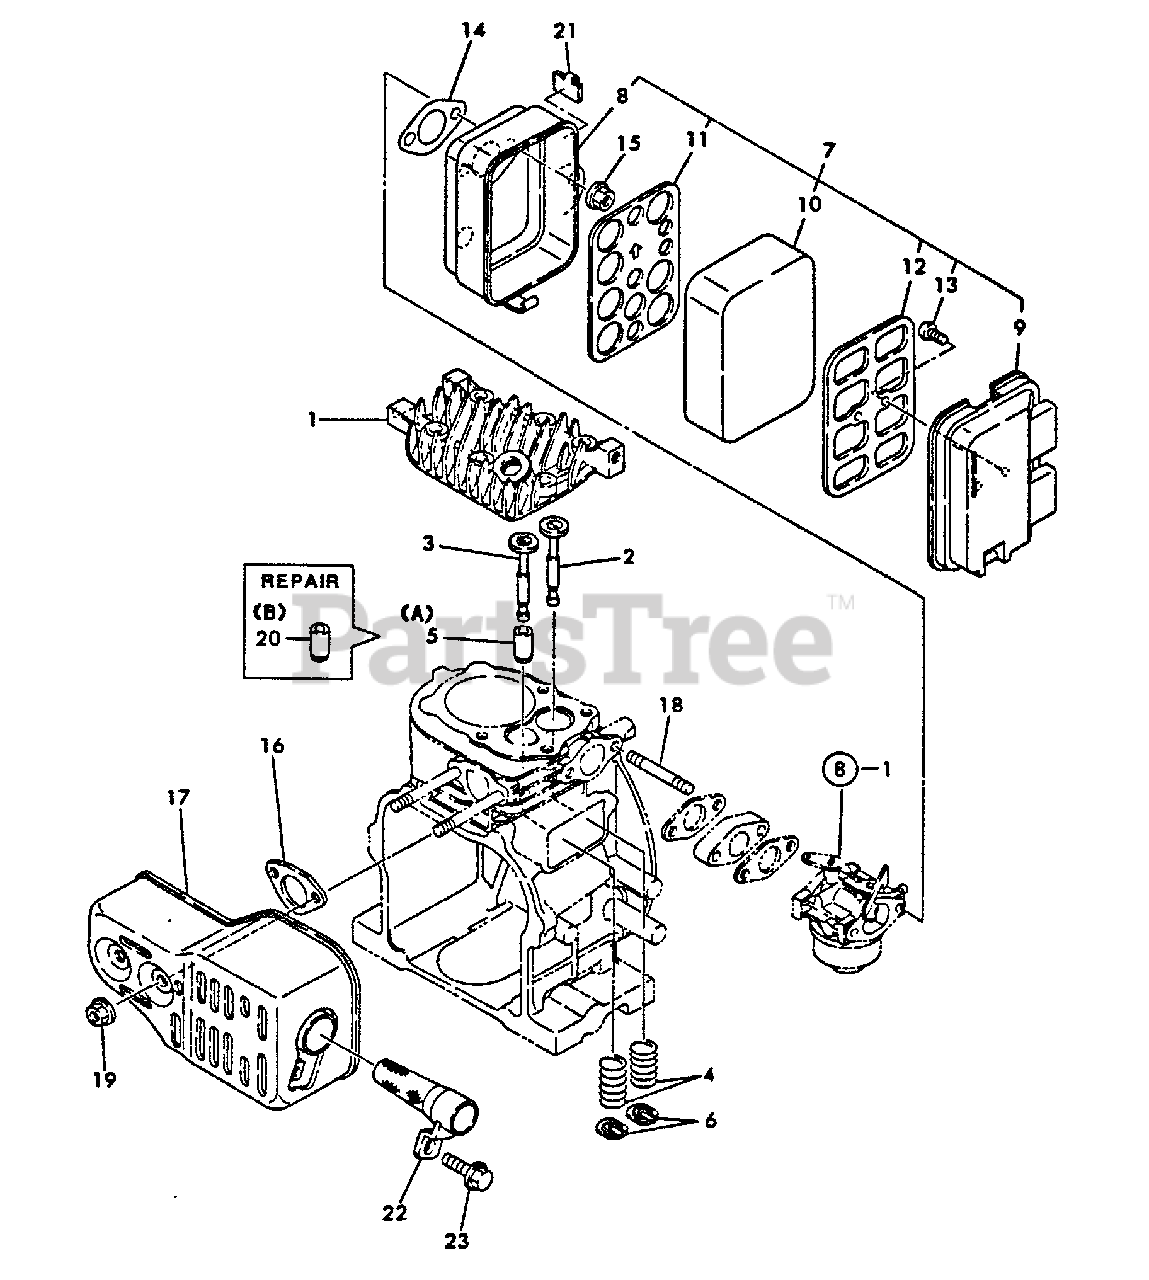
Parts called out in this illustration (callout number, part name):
1	HEAD, CYLINDER
2	VALVE, INTAKE
3	VALVE, EXHAUST
4	SPRING, VALVE
5	GUIDE, VALVE
6	RETAINER, VALVE
7	AIR CLEANER ASSY
8	CASE, AIR FILTER
9	AIR FILTER COVER ASSY
10	FILTER, AIR
11	HOLDER (A), ELEMENT
12	HOLDER (B), ELEMENT
13	SCREW - 5X10
14	GASKET, INTAKE
15	NUT - 6 -- FLANGE
16	GASKET, EXHAUST
17	MUFFLER
18	BOLT - 6X55
19	NUT - 6 -- FLANGE
20	GUIDE, VALVE
21	CLAMP
22	SCREEN, SPARK ARRESTOR
23	BOLT - 6X8 -- PLATED
